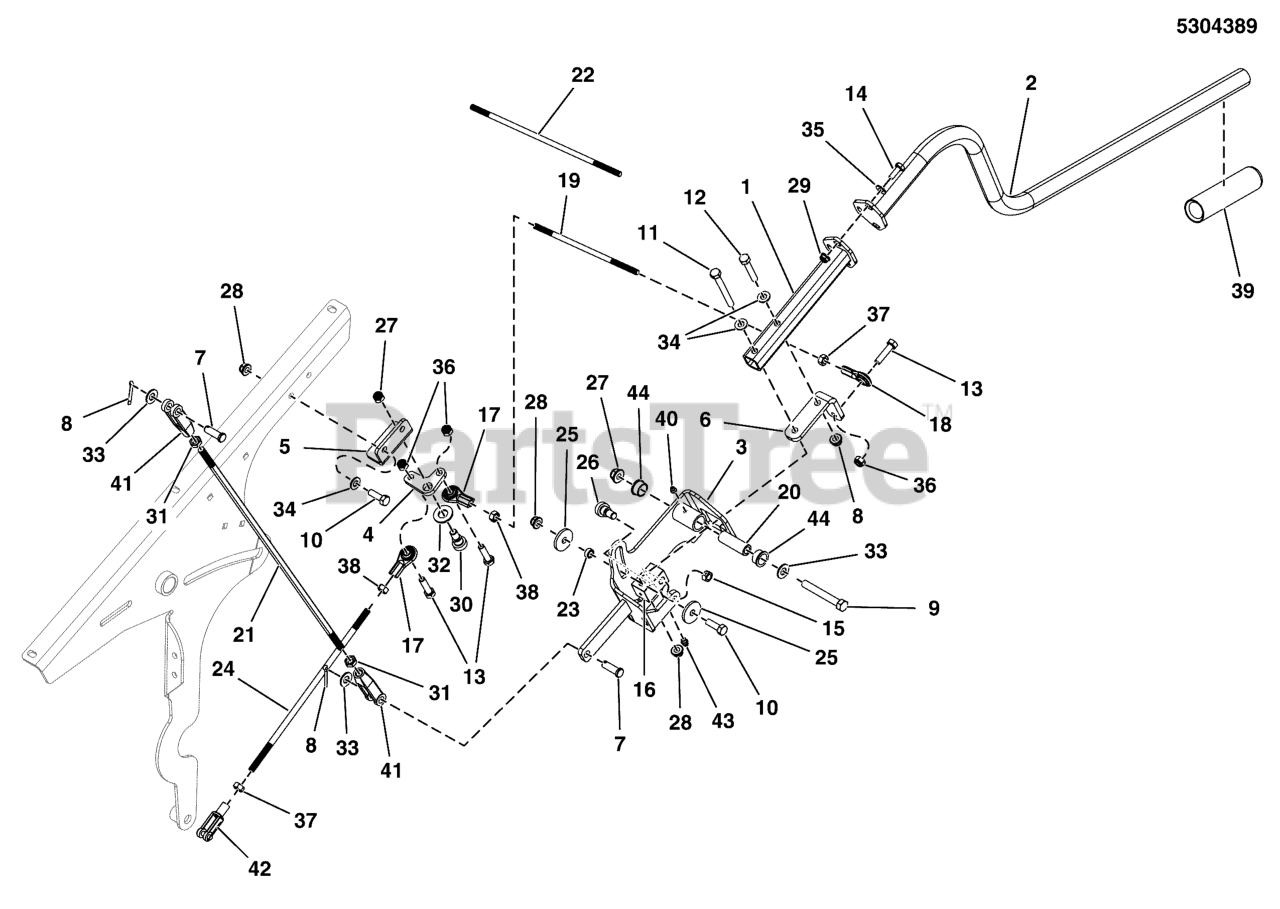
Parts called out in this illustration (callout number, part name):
1	WELD, STUB SHAFT, HOPPER - BLK
2	WELD, HANDLE, DUMP - BLK
3	WELD, HANDLE MOUNT, HOPPER - BLK
4	PLATE, PIVOT, HOPPER - BLK
5	BRACE, PIVOT, HOPPER - BLK
6	PLATE, HINGE, LOWER - BLK
7	PIN, CLEVIS, 3/8 X 1-1/8, PLATED
8	PIN, 3/32 X .750, COT, ZINC/CLEAR
9	BOLT, 3/8-16 X 2-3/4" GD5 CZ
10	BOLT, 5/16-18 X 1 GD5 CZ
11	BOLT, 5/16-18 X 2-3/4 GD5 CZ
12	BOLT, 5/16-18 X 1-3/4 GD5 CZ
13	BOLT, 5/16-18 X 1-1/4 GD5 CZ
14	BOLT, 1/4-20 X 3/4 GD5 CZ
15	NUT, 5/16-18, HEX, CNTR LK,ZINC PHOS/OIL
16	BLOCK, PIVOT, HANDLE, CZ
17	BALL JOINT 5/16-24 LH FEMALE STAMPED STL
18	BALL JOINT 5/16-24 RH FEMALE STAMPED STL
19	ROD, 5/16 X 7.00, LH-RH, CZ
20	SPACER-0.390ID 0.625OD 1.85 LG HARDENED
21	ROD, GATE PULL, HOPPER
22	ROD, 5/16 X 10.25, CZ
23	SPACER-0.328ID 0.497OD 0.218LG PM
24	ROD, HYDRO LINKAGE, CZ
25	WASHER, .34 X 1.25 X 10 GA
26	BOLT, 5/16-18, 3/8 X 1-1/4 SHOULDER
27	NUT, 3/8-16 HEX NYLOCK FLANGE
28	NUT, 5/16-18 HEX NYLOCK FLANGE
29	NUT, 1/4-20 HEX NYLOCK FLANGE
30	BOLT, 3/8-16 X 3/8, 1/2 SHOULDER
31	NUT, 3/8-24 HEX JAM
32	WASHER, 1/2 SAE
33	WASHER, 3/8 SAE
34	WASHER, 5/16" SAE
35	WASHER, 1/4 SAE
36	NUT, 5/16-18 HEX NYLON LOCK
37	NUT, 5/16-24 HEX
38	NUT, 5/16-24 HEX, LH
39	GRIP, FOAM, .940" X 4.62" X .187"
40	GREASE FITTING, PRESS, SHORT
41	CLEVIS 3/8-24, PLASTIC
42	CLEVIS
43	GREASE FITTING, 1/4-28 STRAIGHT
44	BUSHING-0.628IDX0.751ODX0.400LG PWDR MTL
